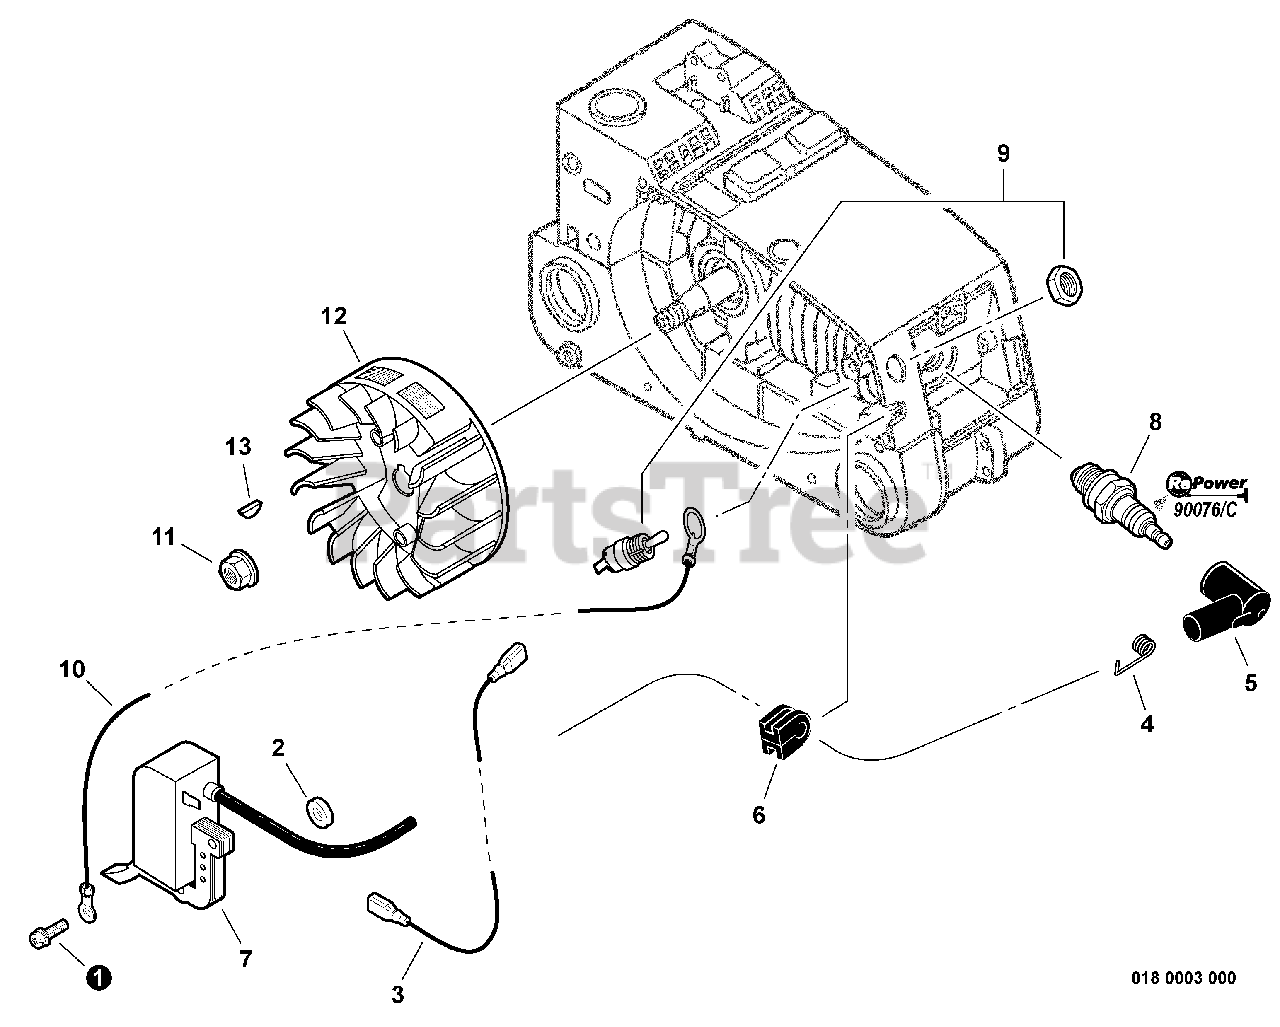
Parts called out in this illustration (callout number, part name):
1	SCREW - 5X22
3	LEAD - IGNITION
4	TERMINAL, SPARK PLUG CAP
5	CAP, SPARK PLUG
7	COIL, IGNITION
8	SPARK PLUG -- BPM-8Y
8	SPARK PLUG -- BPMR-8Y
9	IGNITION SWITCH KIT
10	LEAD - GROUND
11	NUT - 8 -- FLANGE
12	FLYWHEEL
14	RePower TUNE-UP KIT
